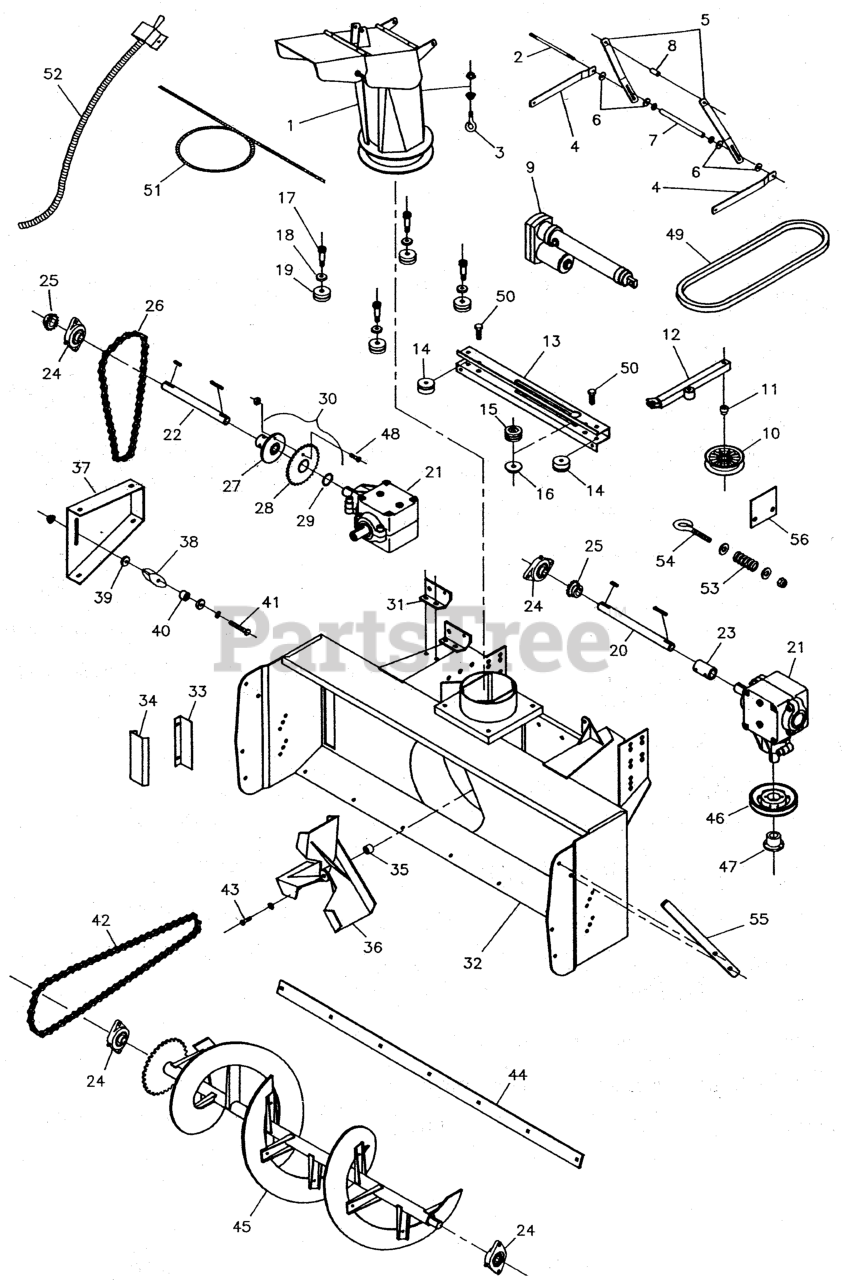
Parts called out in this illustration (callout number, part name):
1	CHUTE WELDMENT
2	HINGE ROD
3	EYEBOLT, 5/16-18 x 3-1/4
4	PIVOT ARM
5	SLIDE BAR
6	FRICTION DISC
9	ELECTRIC ACTUATOR
10	PULLEY, Backside Idler
10A	PULLEY, Idler
11	INSERT, Bearing Shoulder
12	IDLER ARM
13	CABLE SLIDE MOUNT
14	CABLE ROLLER
15	CABLE ROLLER ACTUATOR
16	ACTUATOR SLIDE
17	SHOULDER BOLT, 1/2 x 1
18	WASHER, 1/2 SAE
19	CHUTE PIVOT ROLLER
20	DRIVE SHAFT
21	GEARBOX
22	DRIVE SHAFT
23	GEARBOX SHAFT COLLAR
24	BEARING
25	SPROCKET
26	CHAIN, #40 Roller, 24 Links
27	SHEAR PLATE
28	SHEAR SPROCKET
29	SNAP RING
30	SHEAR PLATE & SPROCKET ASSEMBLY
31	SLIDE MOUNT
32	SNOW BLOWER HOUSING
33	GUARD SUPPORT
34	CHAIN GUARD
35	COLLAR SHIM
36	IMPELLER
37	AUGER DRIVE CHAIN GUARD
38	CHAIN IDLER
39	CHAIN IDLER SPACER - SHORT
40	SPACER, .39 x 1.00 x .50
41	BOLT, 3/8-16 x 3
42	CHAIN, #40 Roller, 49 Links
43	BOLT, 5/16-18 x 1-1/2
44	SNOW BLOWER BLADE
46	PULLEY, Spindle
47	BUSHING, Tapered Hub
48	BOLT, 1/4-20 X 1-1/2
49	BELT
50	CABLE ANCHOR BOLT
51	1/8" WIRE ROPE, 124" LONG
52	HARNESS
53	SPRING, Compression
54	EYE BOLT
55	DRIFT BUSTER
56	IDLER ARM MOUNT
